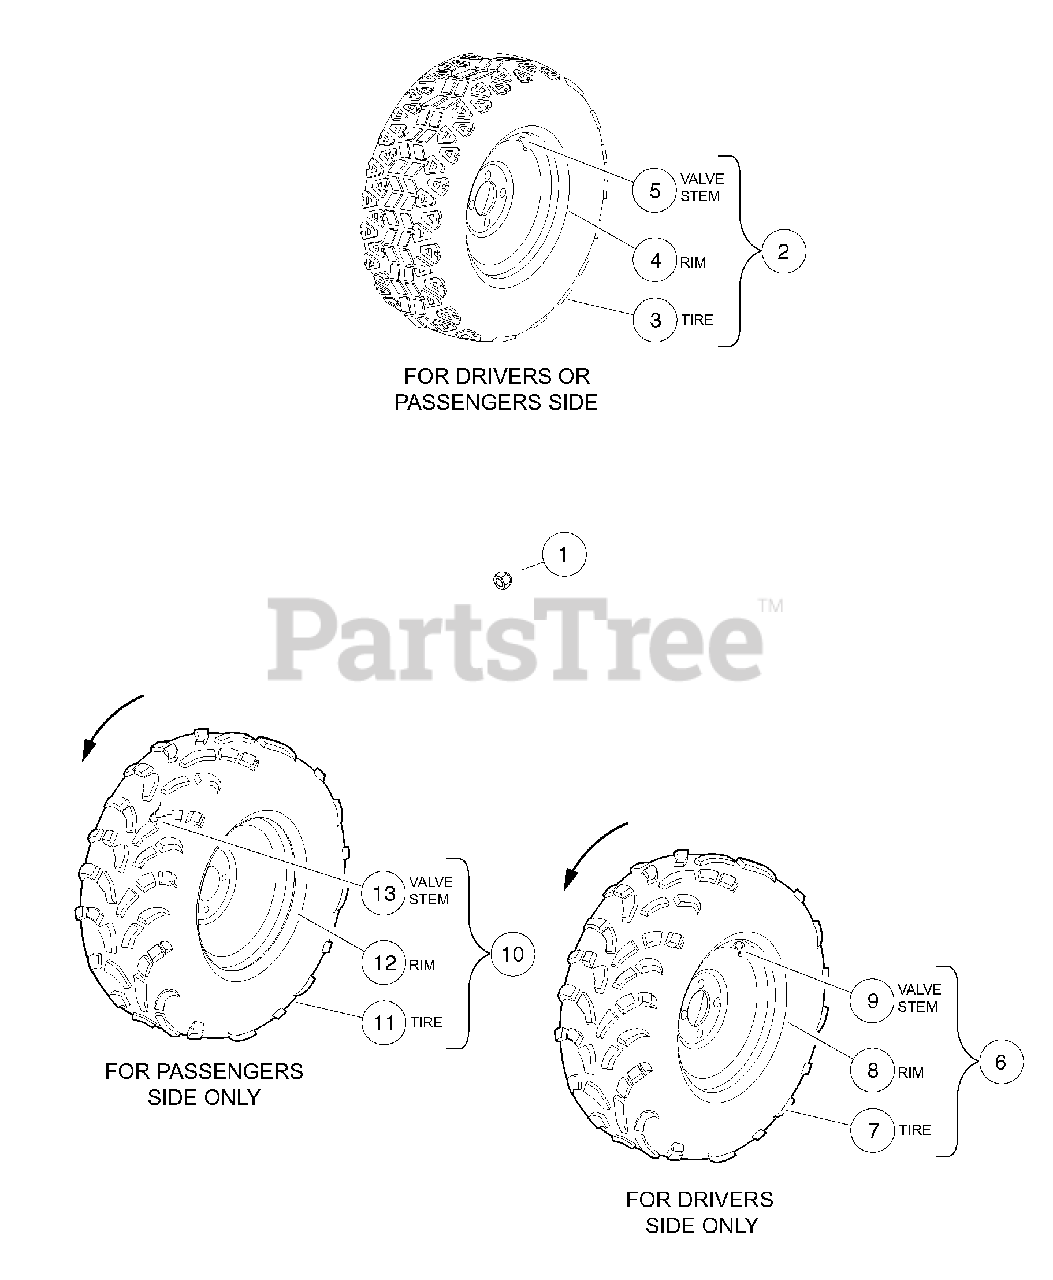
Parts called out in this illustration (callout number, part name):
1	Nut, Lug, 1/2-20 SAE J2283
2	Black Tire Asm HDAT 10.5 In
3	Heavy Duty All Terrain Tire, 25"
4	Wheel, All trail, 10 Window, Black
5	Valve Stem
6	Black Tire Asm Mud 11.0 In Left-Hand
7	Mud Tire, 25"
8	Wheel, All trail, 10 Window, Black
9	Valve Stem
10	Black Tire Asm Mud 11.0 In Right-Hand
11	Mud Tire, 25"
12	Wheel, All trail, 10 Window, Black
13	Valve Stem
